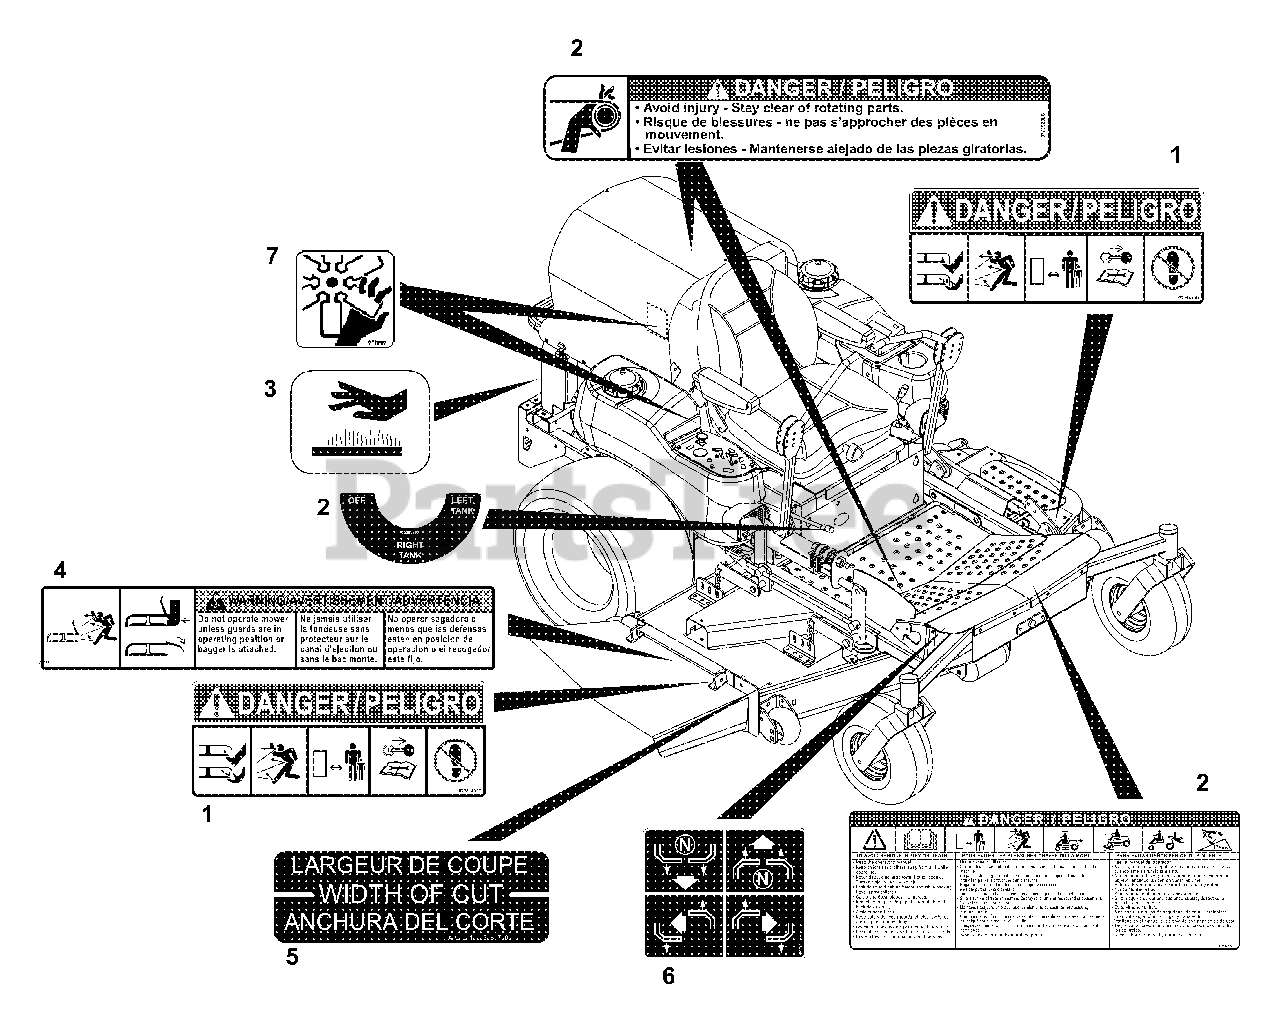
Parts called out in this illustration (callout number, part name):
1	DECAL, MOWER PAN DANGER
2	SET, DECAL-COMMON DANGER/FUEL
3	DECAL, HOT SURFACE
4	DECAL, WARNING
5	WIDTH OF CUT DECAL
6	DECAL, INSTRUCTIONAL-STEERING
7	DECAL, DANGER FAN
